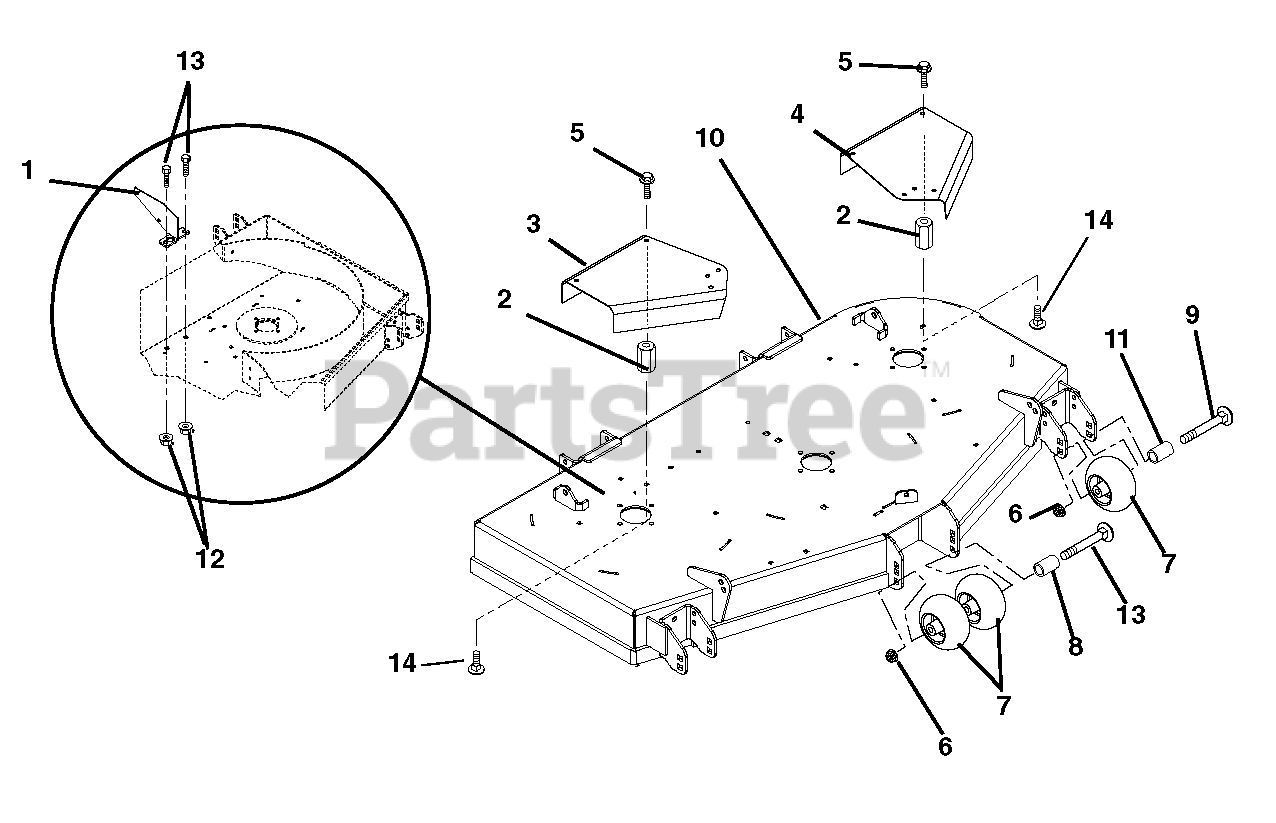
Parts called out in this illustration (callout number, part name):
1	Rear Deflector Baffle
2	Nut, Coupling, .31-18 x 3.00
3	52-in. Right Hand Spindle Guard (992322)
4	52-in. Left Hand Spindle Guard (992322)
5	Bolt, SEMS .31-18 x .62
6	Nut .50-13 Nyloc Flange
7	Anti-Scalp Wheel
9	Bolt, Round Head Square Neck .50-13 x 5.00
10	52-in. Mower Deck (992322)
11	Spacer, .510 x .625 x 3.35
12	Nut, .38-16 Nyloc Flange
13	Bolt, Round Head Square Neck, 3/8-16 x 1.00
14	Bolt, Round Head Square Neck, .31-18 x .75 Loc-Tite®
